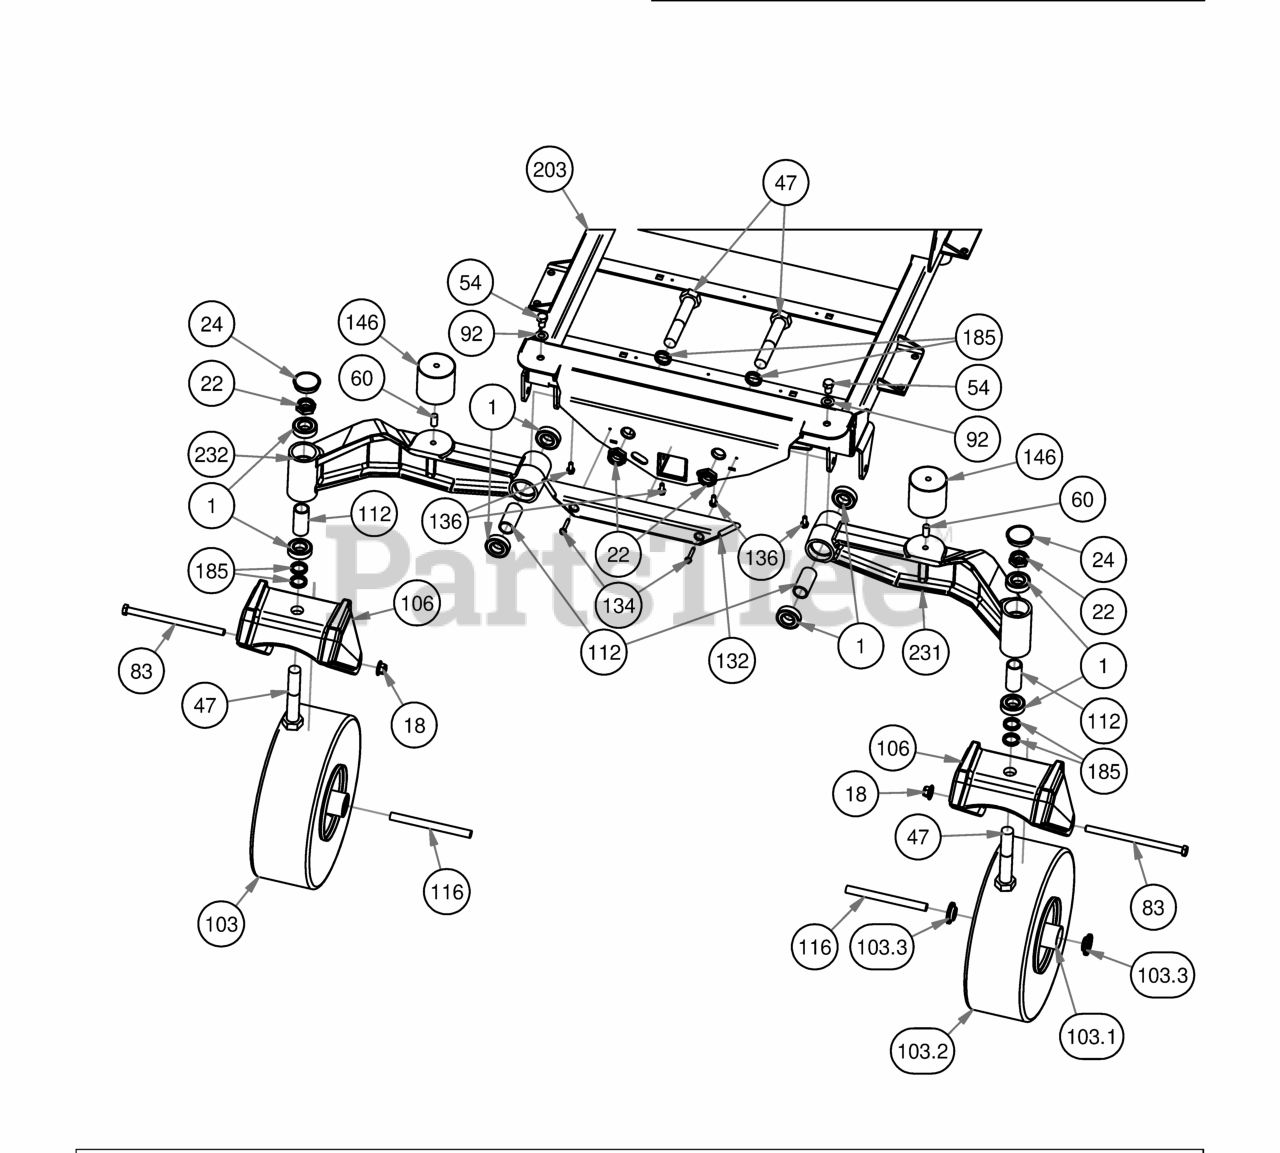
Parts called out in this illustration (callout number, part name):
1	1641 BEARING W/2 CONTACT RUBBER SEALS
7	M8-1.25 Zinc Nut
18	1/2-13 Nylon Flange Nut
22	1" Fine Thread 1/2 Nylock Nut
24	2017 Bearing Cover
47	1-14 x 5.5 Hex Bolt Grade 8 Zinc Yellow
54	1/2" x 3/4" Hex Bolt
60	1/2-13 x 1" Stud
83	1/2" x 9" GR 5 Hex Bolt
92	1/2" Washer (Grade 8)
99	5/16" Lock Washer
103	2019 Front Tire Assy 15x6.00-6 pneumatic
103.1	6x4.5 Wheel w/Bearings
103.2	15x600-6 Tire Only
103.3	1-3/4" Bearing-Large Bore Front Rim
106	2019 Rebel, Rogue, Renegade Front Fork
112	2016 Front Bearing Spacer
116	Front Wheel Spanner
132	2017 XP Bumper
134	1/4" x 1 1/2" Self Tapping Screw
136	5/16 x 3/4 washer head type F screw
146	Vibration Mount-Blue Dot
185	Spacer, 1x1.375x.25
203	2019 Veritical Suspension Frame
231	2019 Front I-Beam Left
232	2019 Front I-Beam Right
